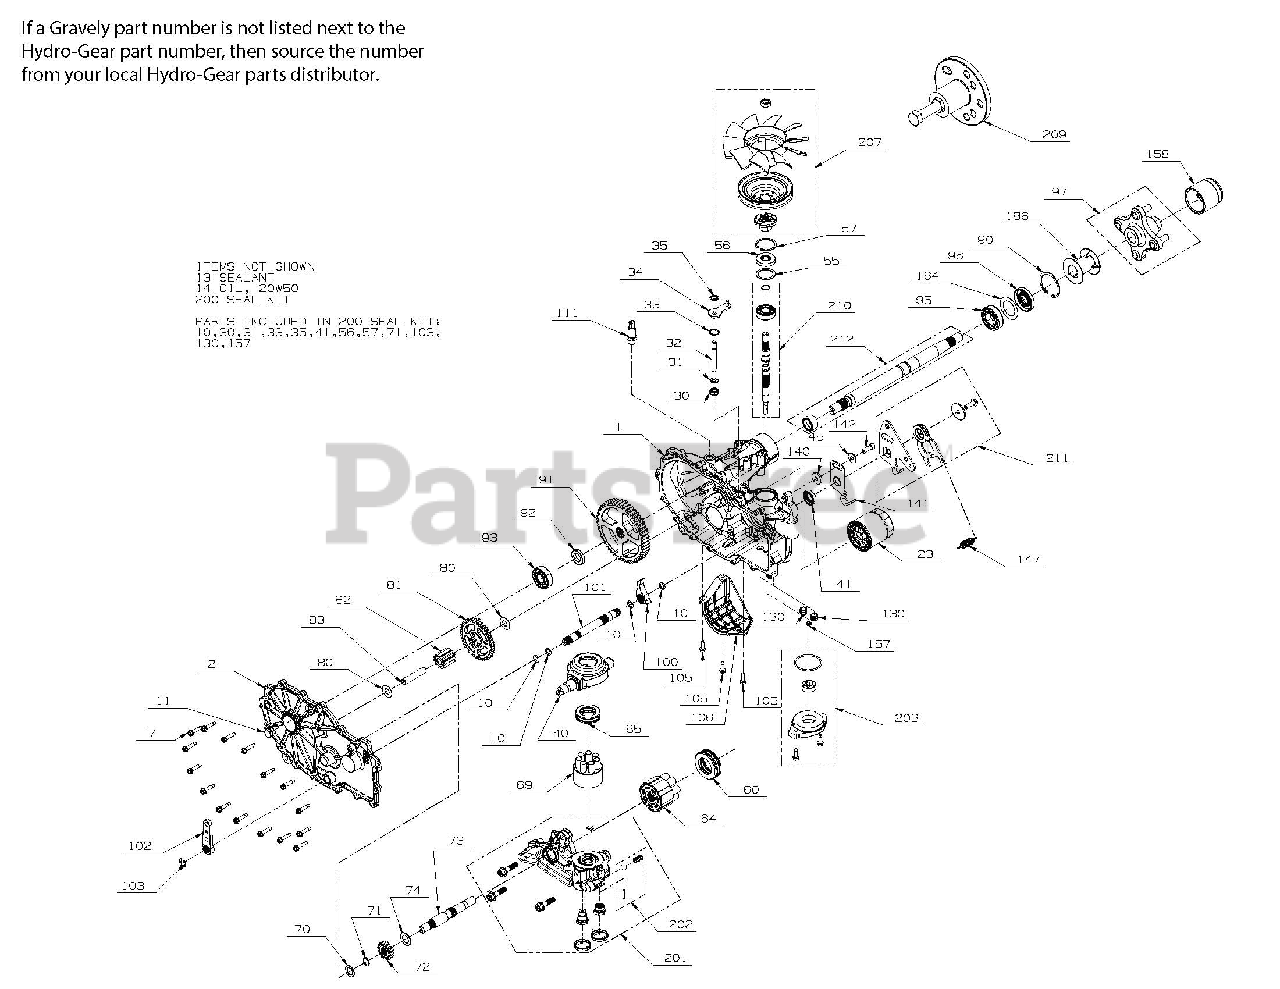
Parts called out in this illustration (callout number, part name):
7	SCREW, HEX WASHER
13	TUBE, SEALANT
23	FILTER, SPIN-ON 2.6 X 3.0
30	SEAL, LIP .375 X .75 X .25
31	RING, RETAINING EXTERNAL .375
33	RING, RETAINING .750, INTERNAL
34	ARM, BYPASS
35	RING, RETAINING .375 EXTERNAL
40	SWASHPLATE, TRUNNION
41	SEAL, LIP 15 X 32 X 7
45	WASHER 7LA1.34 X .BB X .06
55	WASHER, FLAT 1.23 X 1.57 X .04
56	SEAL, LIP 17 x 40 x 7
57	RING RETAINING INTERNAL
60	BEARING, THRUST 35 x 62 x 18
64	KIT, 16cc CYLINDER BLOCK ASSEMBLY
65	BEARING, THRUST 30 x 52 x 13
69	KIT, BLOCK 7 PISTON
70	WASHER, .63 X 1.00 X .05 FLAT
71	RETAINING RING, MOTOR SHAFT
74	WASHER, .71 X 1.16 X .04 FLAT
80	WASHER, .51 X 1.00 X .03 FLAT
83	PIN, JACKSHAFT
90	RING, RETAINING 2.25 INTERNAL
95	BEARING, BALL 6205R-1 25.4 x 52 x 15
96	SEAL, LIP, TC4, 1.0 X 2.06 X .38
97	KIT, HUB 4 BOLT
105	SCREW, HEX WASHER 1/4-20 X .75
106	GUARD, FILTER, LH
111	KIT, FITTING 1/2 BEADED 9/16 SAE
140	SPACER 0.320 ID X 1.005 OD X 0.1495 THK
141	ARM, RETURN LEFT
142	SHCS 5/16-24 x 7/8
147	SPRING, EXTENSION
200	KIT, SEAL, ZT-2800
203	KIT, CHARGE
207	KIT, FAN/PULLEY
209	KIT, HUB PULLER
210	KIT, INPUT SHAFT
211	KIT, RTN CCW
